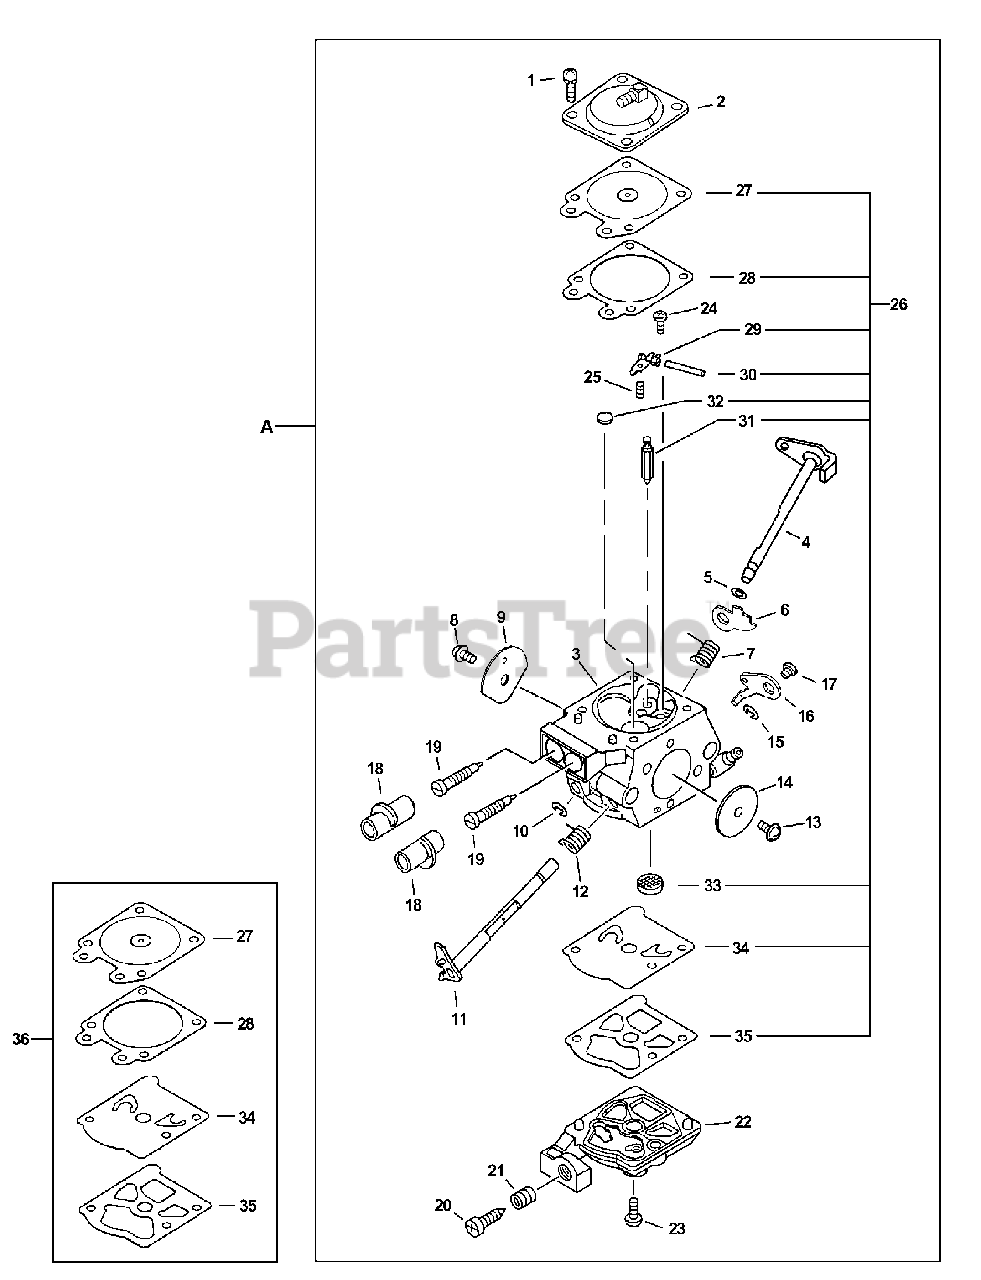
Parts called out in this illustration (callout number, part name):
2	COVER, DIAPHRAGM
3	BODY, CARBURETOR
4	SHAFT, CHOKE
6	LEVER, FAST IDLE
7	SPRING, CHOKE RETURN
9	VALVE, CHOKE
10	RING, RETAINING
11	SHAFT, THROTTLE
12	SPRING, THROTTLE RETURN
14	VALVE, THROTTLE
15	RING, RETAINING
16	LEVER, THROTTLE
18	CAP, LIMITER
19	NEEDLE - MIXTURE
20	SCREW, IDLE ADJUST
21	SPRING, IDLE ADJUST
22	COVER, FUEL PUMP
23	SCREW, PUMP COVER
24	SCREW, METERING LEVER PIN
25	SPRING, METERING LEVER
26	REPAIR KIT
27	DIAPHRAGM, METERING
28	GASKET, METERING
29	LEVER, METERING
30	PIN, METERING LEVER
31	VALVE, INLET NEEDLE
32	PLUG, WELCH
33	STRAINER
34	DIAPHRAGM, PUMP
35	GASKET, PUMP
36	DIAPHRAGM/GASKET KIT
A	CARBURETOR WT-739
